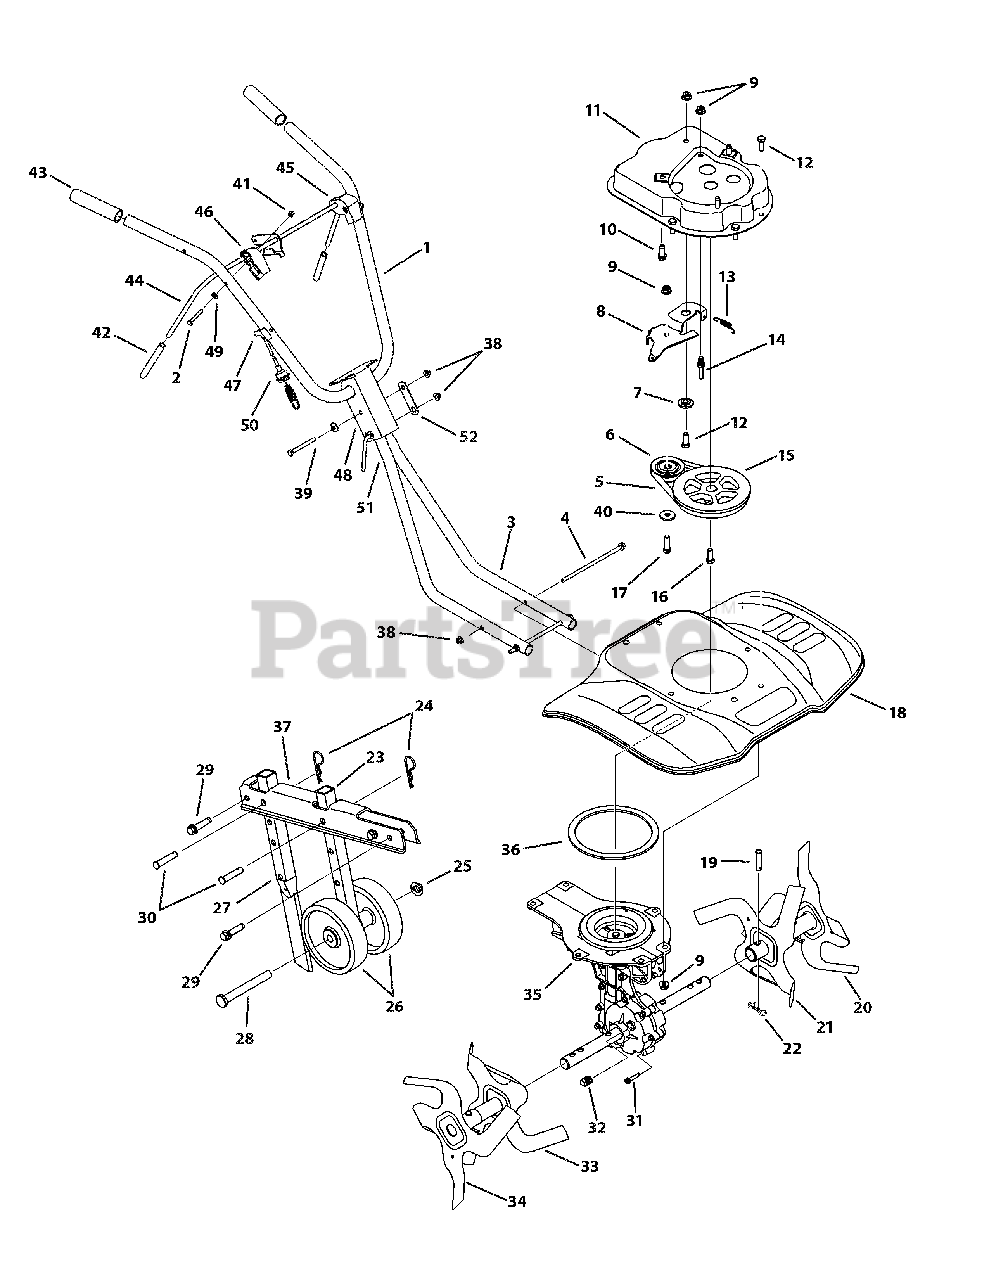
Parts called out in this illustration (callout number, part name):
1	Upper Handle
2	Hex Head Cap Screw, 1/4-20 x 1.75
3	Lower Handle
4	Flange Screw, 5/16-18 x 7.5, GR5
5	V-Belt
6	Idler Pulley
7	Shoulder Spacer
8	Idler Bracket
9	Flange Lock Nut, 3/8-16
10	Self Tapping Screw, 3/8-16 x 1.00
11	Belt Cover
12	Hex Head Cap Screw, 3/8-16 x 1.00
13	Extension Spring
14	Stud, 33 x 1.5, 3/8-16
15	Flywheel Pulley
16	Hex Head Cap Screw, 3/8-24 x 1.00
17	Hex Head Cap Screw, 3/8-16 x 1.55
18	Tine Shield 61 cm
19	Clevis Pin
20	Outer Tine Assembly LH
21	Inner Tine Assembly LH
22	Cotter Pin, Bow Tie
23	Rear Wheel Tube
24	Cotter Pin
25	Push Cap
26	Wheel 5 x 1.38
27	Depth Stake Tube
28	Axle Shaft
29	Self Tapping Screw, 3/8-16 x 1.50
30	Clevis Pin
31	Self Tapping Screw, 1/4-20 x 1.25
32	Pipe Plug, 1/4-18 NPT
33	Inner Tine Assembly RH
34	Outer Tine Assembly RH
35	Case Assembly
36	Gasket
37	Wheel Bracket
38	Flange Lock Nut, 5/16-18
39	Hex Head Cap Screw, 5/16-18 x 3.00
40	Flat Washer, .406 x .875 x .059
41	Hex Lock Nut, 1/4-20
42	Handle Grip
43	Grip, 1.0 ID x 5.0 LG
44	Clutch Bail
45	Bail Holder LH
46	Bail Holder RH
47	Handle Fitting
48	Bell Washer, .340 x .872 x .060
49	Flat Washer, .25 x .630 x .0515
50	Clutch Cable
51	Handle Crank
52	Retainer Bracket
